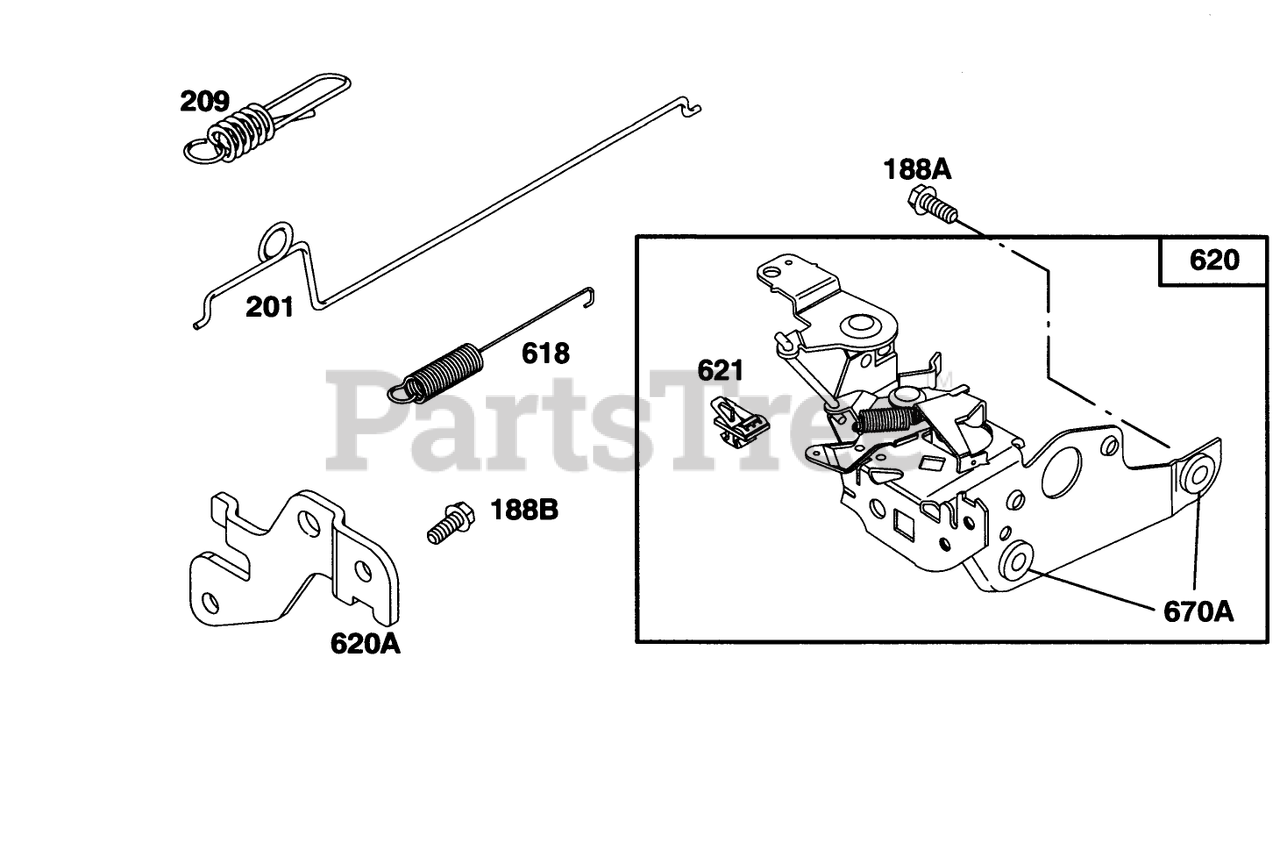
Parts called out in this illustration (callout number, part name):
188A	Screw-Hex.
188B	Screw-Hex.
201	Link-Govemor
209	Spring-Govemor
618	Spring-Choke
620	Bracket-Carburetor
621	Switch
670A	Spacer
